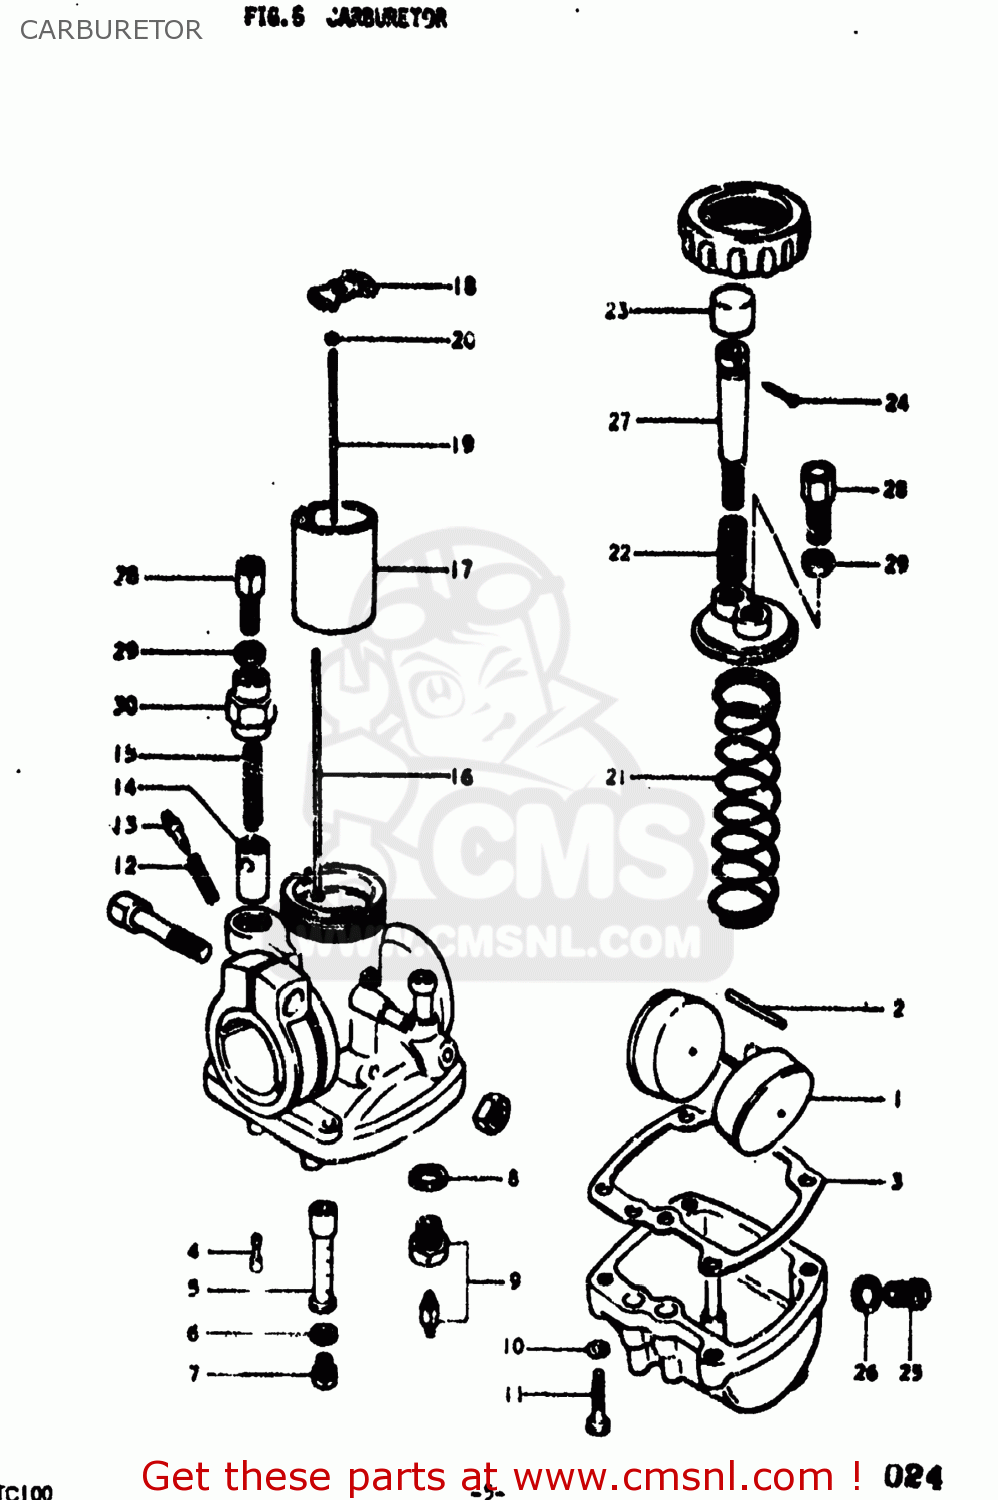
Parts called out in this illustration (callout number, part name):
0	CARBURETOR ASSEMBLY
1	FLOAT
2	PIN,FLOAT
3	GASKET,FLOAT CHAMBER (NAS)
4	JET
5	JET,NEEDLE
6	WASHER
7	JET,MAIN
8	GASKET,NEEDLE VALVE (NAS)
9	VALVE ASSY,NEEDLE
10	LOCK WASHER
11	SCREW
12	SPRING
13	SCREW,PILOT AIR
14	PLUNGER,STARTER
15	SPRING
16	ROD,THROTTLE VALVE ADJUST
17	VALVE,THROTTLE
18	STOPPER,NEEDLE CLIP
19	NEEDLE.JET
20	CLIP,NEEDLE
21	SPRING,THROTTLE VALVE
22	SPRING,THROTTLE STOP SCREW
23	CAP,THROTTLE VALVE STOP SCREW
24	PIN 12X10
25	PLUG
26	GASKET,DRAIN,PLUG (NAS)
27	SCREW,THROTTLE STOP
28	ADJUSTER,CABLE
29	NUT
30	CAP,STARTER PLUNGER
